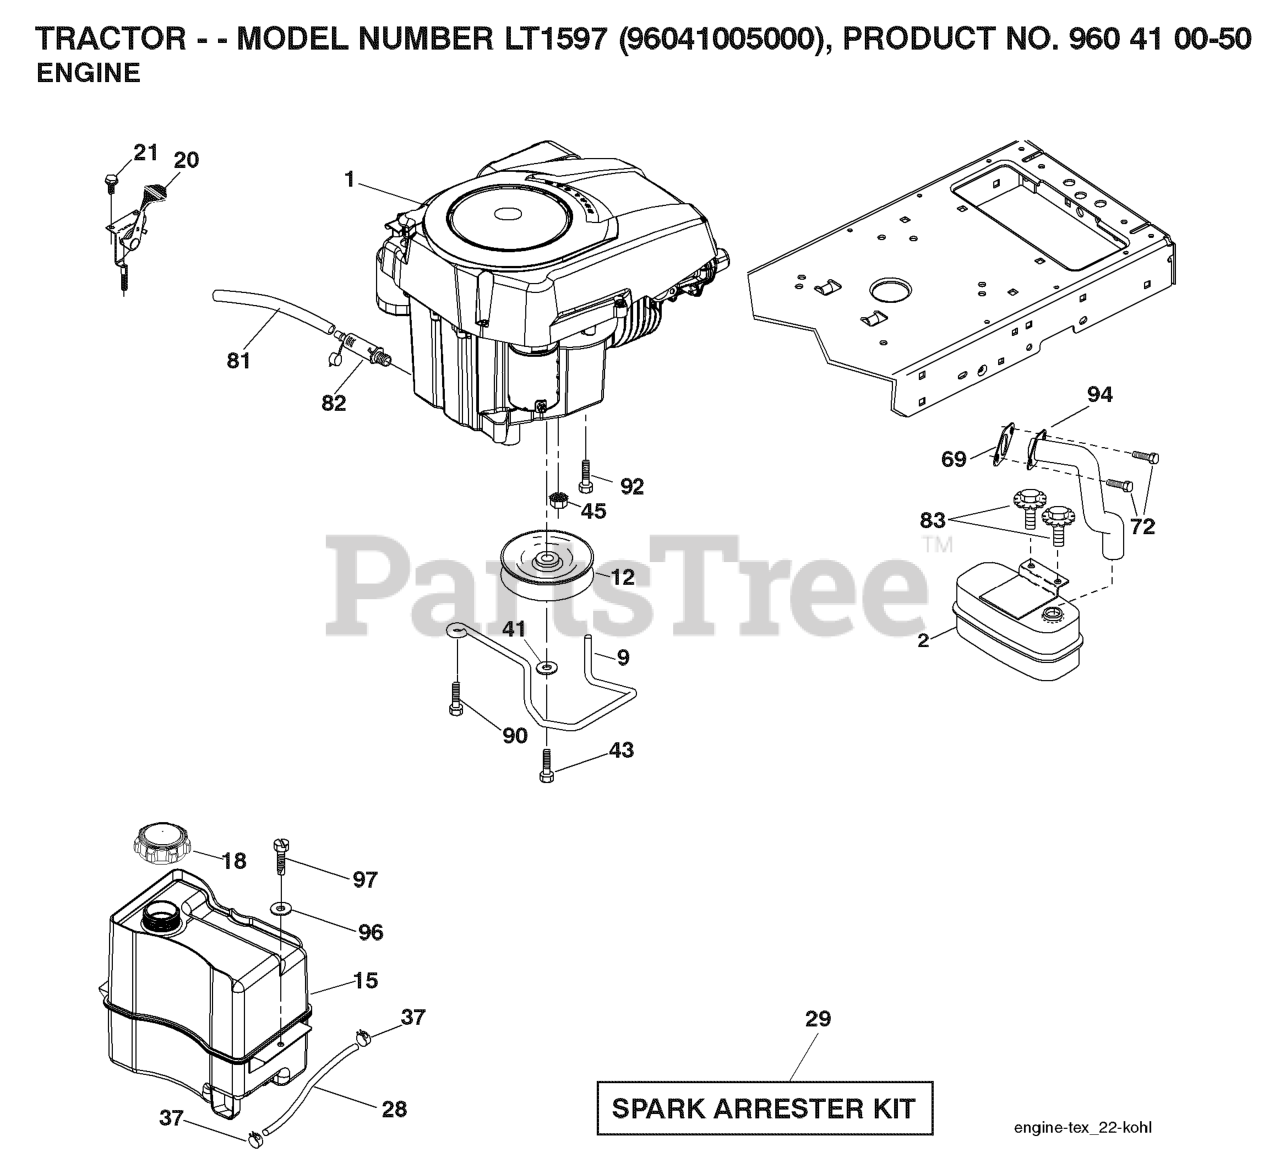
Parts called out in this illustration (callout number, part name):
2	MUFFLER.SINGLE.CYL.KOHL/B&S
9	KEEPER.BELT.ENGINE.3.25 (3 2)
12	PULLEY ENGINE
15	RP TANK FUEL FRT 1.5 GAL
18	FUEL CAP
20	CONTROL.TH/CK.C.
21	SCREW
28	LINE.FUEL.20
29	KIT.SPARK ARRESTOR 794945 B&S
37	HOSE CLAMP
41	LOCKWASHER
43	BOLT HEX 7/16-20X4-1/4"
45	NUT
72	SCREW.SOCKET HD.5/16-1
81	TUBE, DRAIN OIL ASM.
82	PLUG DRAIN OIL EASY
83	BOLT.5/16-18UNCX3/4 W/SEMS.BLK
90	SCREW 3/8-16X1
92	SCREW 3/8-16X1
94	RP.TUBE.EXHAUST.KOHL.COURAGE
97	SCREW HEXWSHR 1/4-20X3/4
